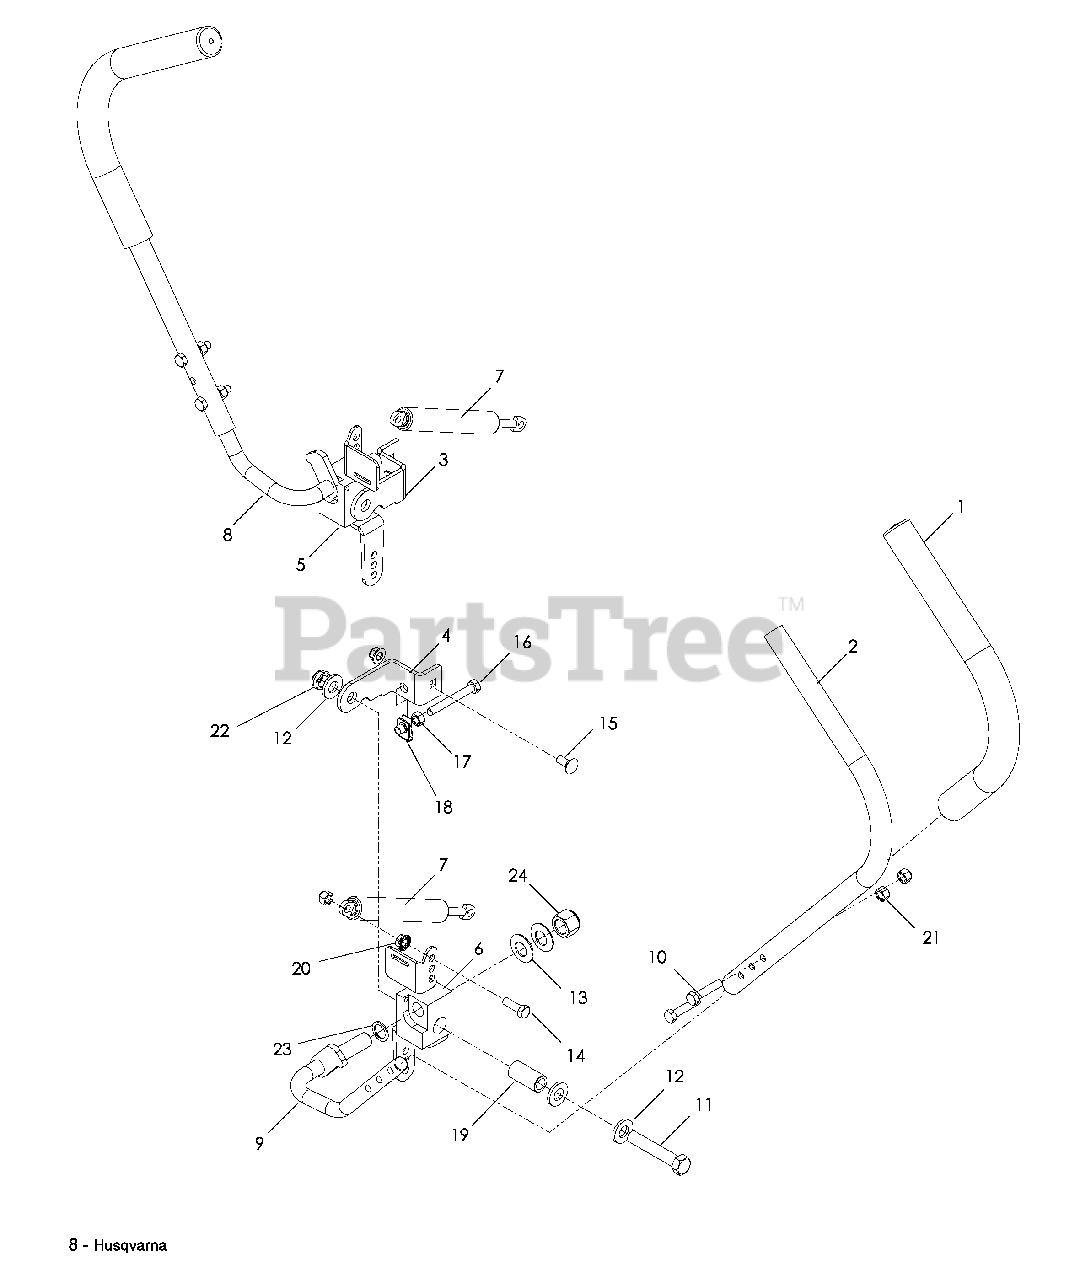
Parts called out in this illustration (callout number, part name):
2	LEVER, UPPER
3	STOP, STEER CNTRL RH
4	STOP, STEER CNTRL LH
8	LOWER LEVER, RH
9	LOWER LEVER, LH
10	HCS 5/16-18 x 1½
11	HCS ½-13 x 2¾
12	WASHER ½ SAE
13	WASHER 5/8 BELLEVILLE
14	HCS 5/16-18 x 1
15	RHSNB 5/16-18 x ¾
16	HCS 5/16-18 x 2½ TPBLT
17	NUT, 5/16-18 HEX
18	U TYPE RETAINER
19	BUSHING ½ ID x ¾ OD
20	NUT 5/16-18 HEX WHIZLK
21	NUT 5/16-18 HEX NYLOC
22	NUT ½-13 JAM NYLOC GR 2
23	WASHER, SPECIAL
24	NUT 5/8-11 NYLOC
